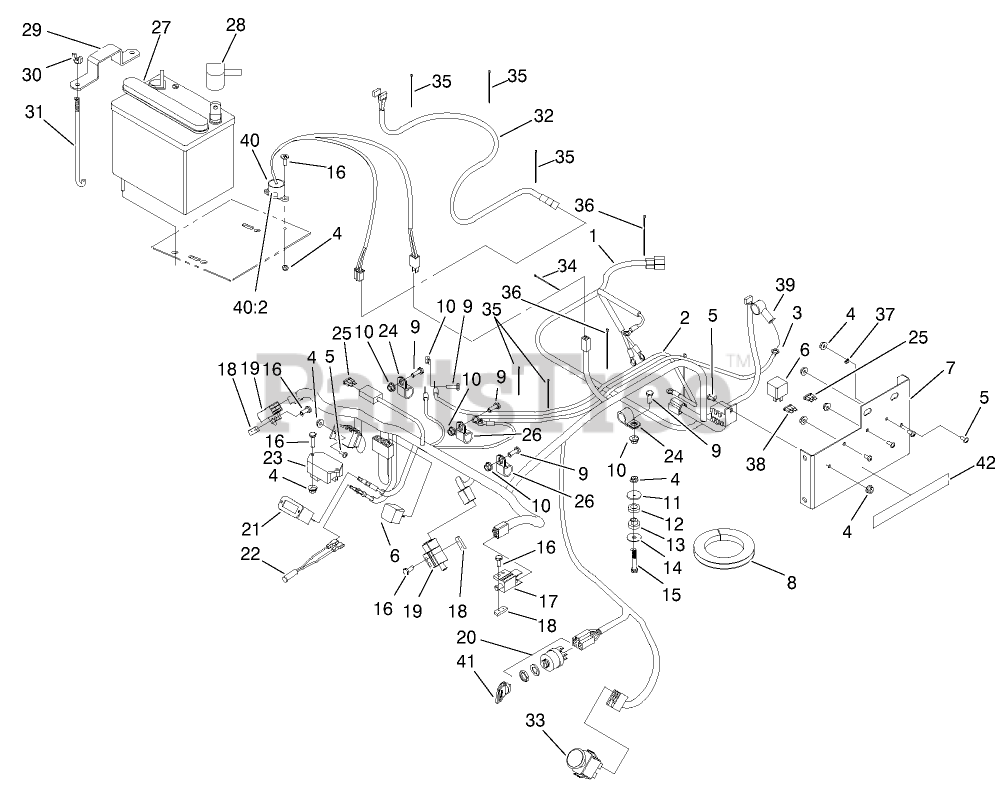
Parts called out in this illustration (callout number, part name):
1	Harness-Wiring
2	Wire-Ground
3	Cable-Battery
4	NUT-LOCK, NI
5	Screw
6	Relay
7	Panel-Fuses/Relay
8	Trim-Lok
9	SCREW-HH
10	NUT-HF
11	Washer-Fender
12	Ring Mount-Vibration
13	Bushing Mount-Vibration
14	Washer-Fender
15	Screw-Shoulder
16	Screw
17	Switch-Brake
18	Plate
19	Switch-Drive Lever
20	Ignition Switch
21	Meter-Hour
22	Indicator-Red Led
23	Module-Ignition
24	Clip
25	Fuse
26	Clip
27	Battery
28	Insulator Battery
29	Strap-Hold Down
30	Wingnut
31	Bolt
32	Harness-Wire Seat
33	Switch
34	Tie-Plastic
35	Tie-Plastic
36	Tie-Plastic
37	Clip
38	Fuse-10 Amp
39	Insulator Solenoid
40	Switch-Tilt
40:2	Decal
41	KEY-IGNITION
